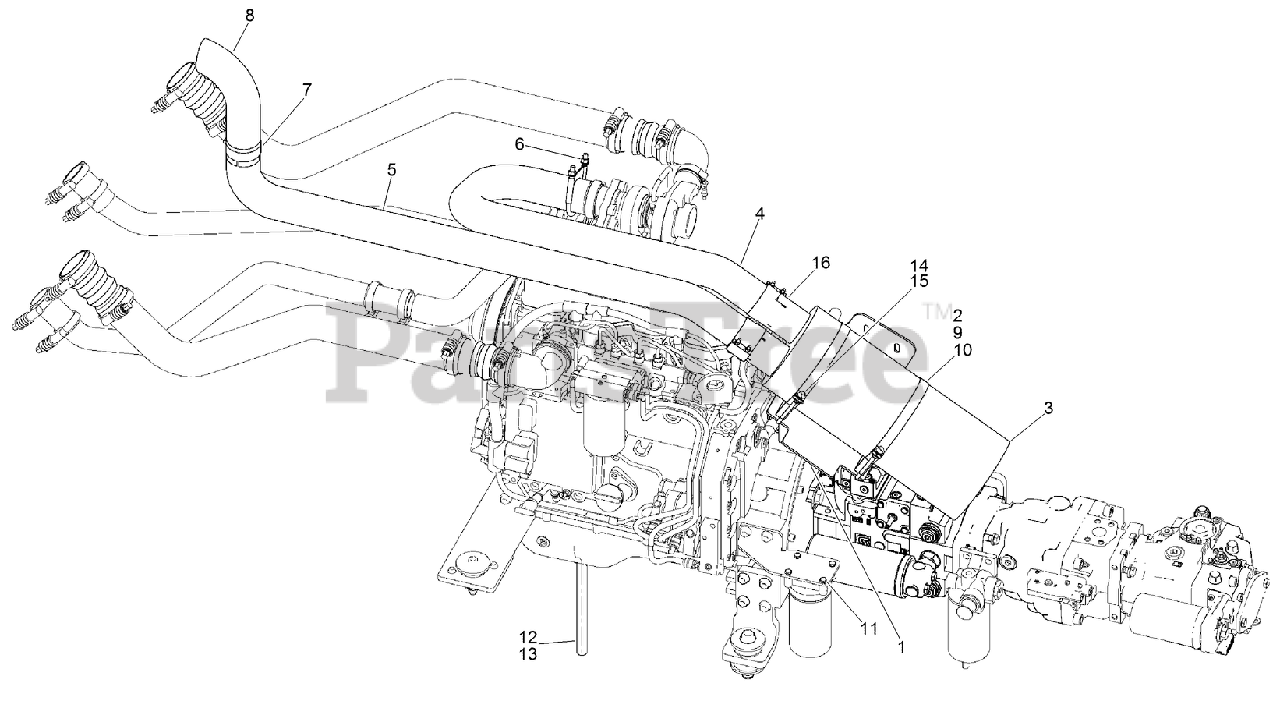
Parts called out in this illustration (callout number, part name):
1	BRACKET - Mounting, Muffler / Air Filter
2	BAND-MOUNTING, MUFFLER
3	ASSEMBLY - Muffler w/Insulation Blanket
4	TUBE - Exhaust, In
5	TUBE - Exhaust, Out
6	CLAMP-GUILLOTINE
7	CLAMP-MUFFLER
8	PIPE-STACK
9	SCREW-HHF
10	NUT, METRIC FLANGE PREVAILING - M6 Zinc
11	BOLT-Hex, 5/16 NC x 1-1/2 inch
12	HOSE-DRAIN, OIL
13	CLAMP-HOSE
14	SCREW, METRIC FLANGE w/BODY - M8 x 110
15	NUT-TORQUE, PREVAILING
16	CLAMP - Torc Tite 3
